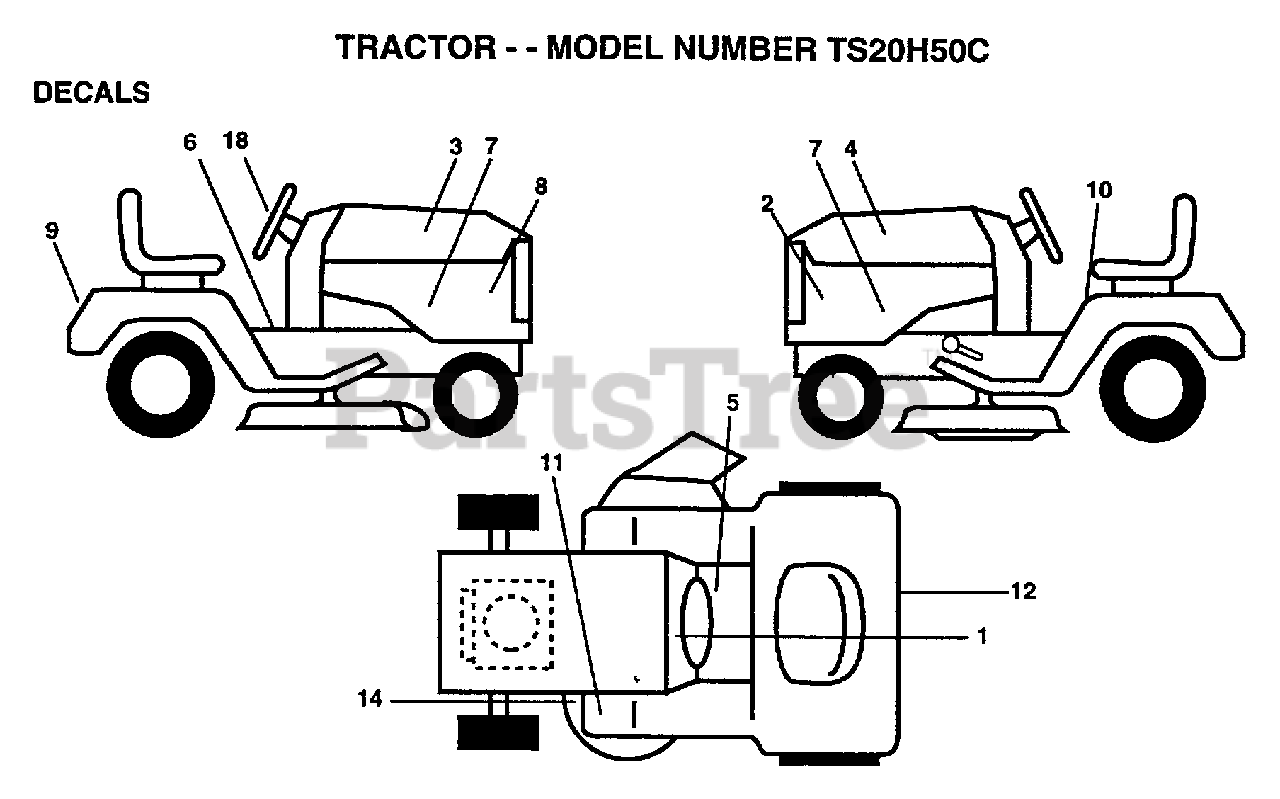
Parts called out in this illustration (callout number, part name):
1	DECAL.DASH.INST.
2	NAMEPLATE.HUSK.LG
3	DECAL.HD.RH.20/50
4	DECAL.HD.LH.20/50
5	DECAL BRAK PARK
6	DECAL SADLE HYDRO
7	DECAL.PNL.SIDE.20
8	DECAL SADLE HYDRO
9	DECAL.FEND.YT/GT
10	DECAL
12	DECAL D-BAR CNTRL
14	"DECAL.V.BELT.44"""
18	DECAL.INS.WHL.STG
